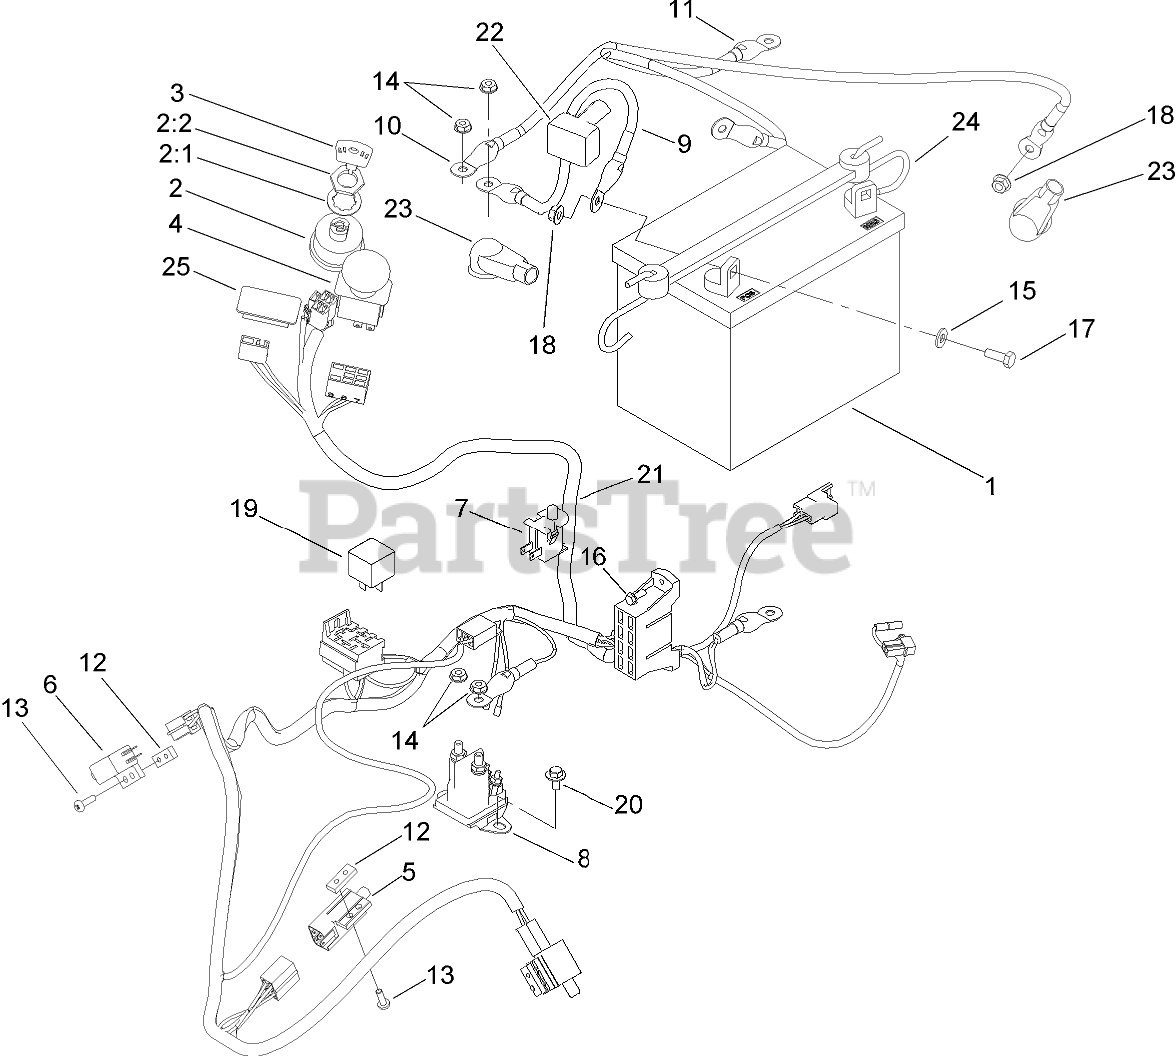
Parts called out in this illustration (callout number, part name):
1	BATTERY
2	Key Switch ASM
2:1	WASHER-TOOTH, INTERNAL
2:2	NUT-HH
3	KEY-IGNITION
4	SWITCH-PTO
5	SWITCH-INTERLOCK
6	SWITCH-POLE, SINGLE
7	SWITCH-BAIL
8	SOLENOID-STARTER
9	WIRE ASM
10	CABLE-BATTERY, RED
11	CABLE
12	PLATE-TAPPED
13	SCREW-PPHTF
14	NUT-KEPS
15	WASHER-FLAT
16	SCREW-TAPTITE
17	SCREW-HH
18	NUT-HF
19	RELAY
20	SCREW-HHFTF
21	HARNESS-WIRE
22	BOOT-TERMINAL
23	BOOT-INSULATOR, TERMINAL
24	HOLDDOWN-BATTERY
25	PLUG-HOLE
